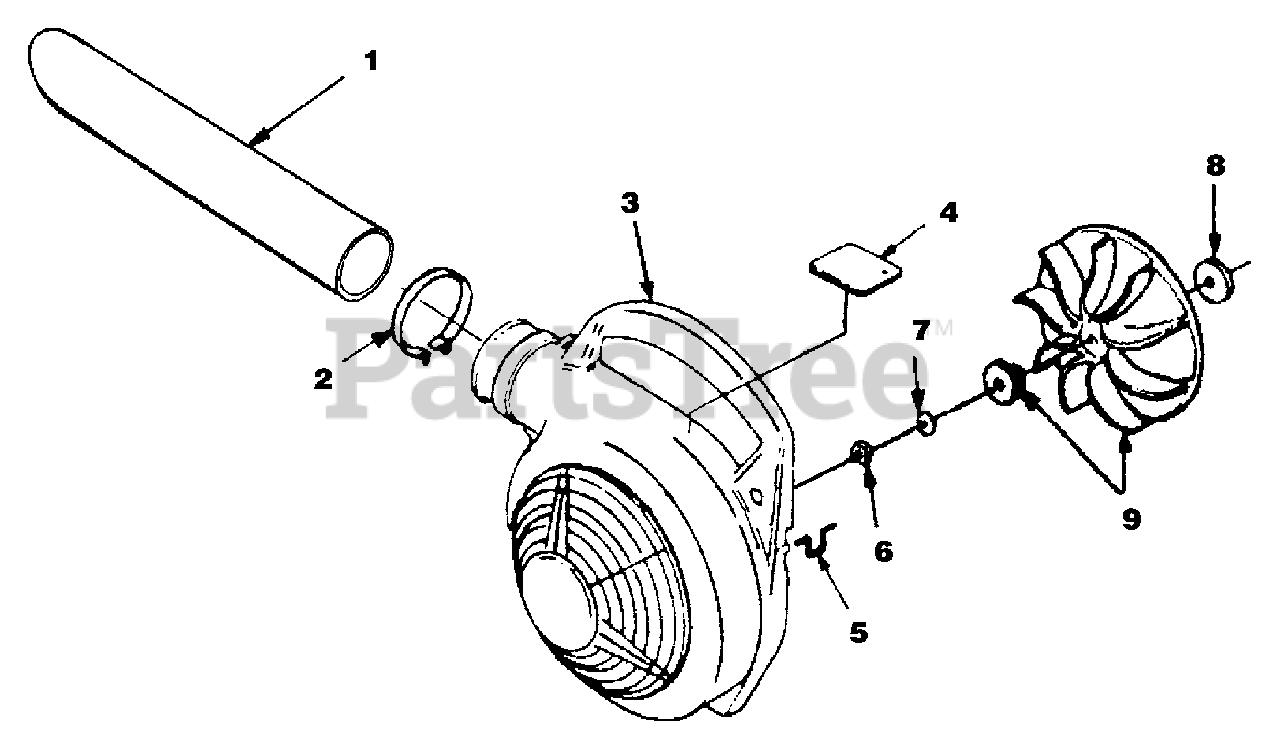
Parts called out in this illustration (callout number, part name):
1	TUBE
2	CLAMP w/Fasteners
3	VOLUTE HOUSING (Outer)
4	DECAL-Warning
5	LOOP-Wire
6	NUT-Hex (3/8-24)
7	WASHER-Bellville (3/8")
8	WASHER-Flat
9	BLOWER FAN KIT
